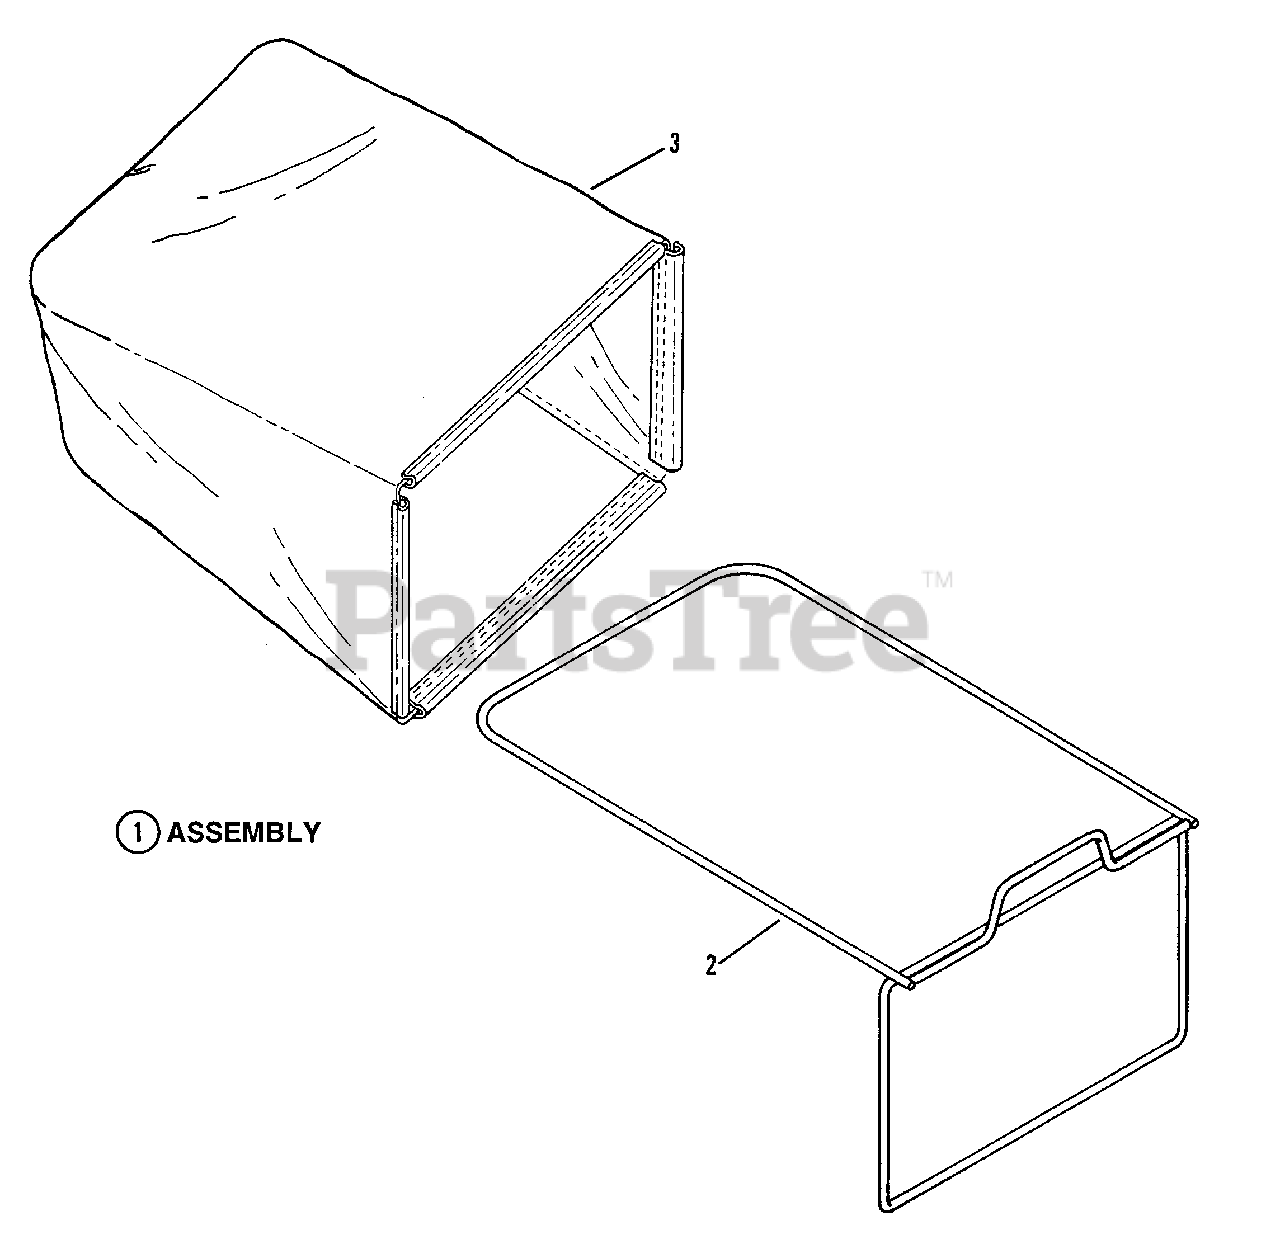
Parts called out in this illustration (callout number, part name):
1	KIT, Grass Bag
2	FRAME, Grass Bag
3	BAG, Grass
